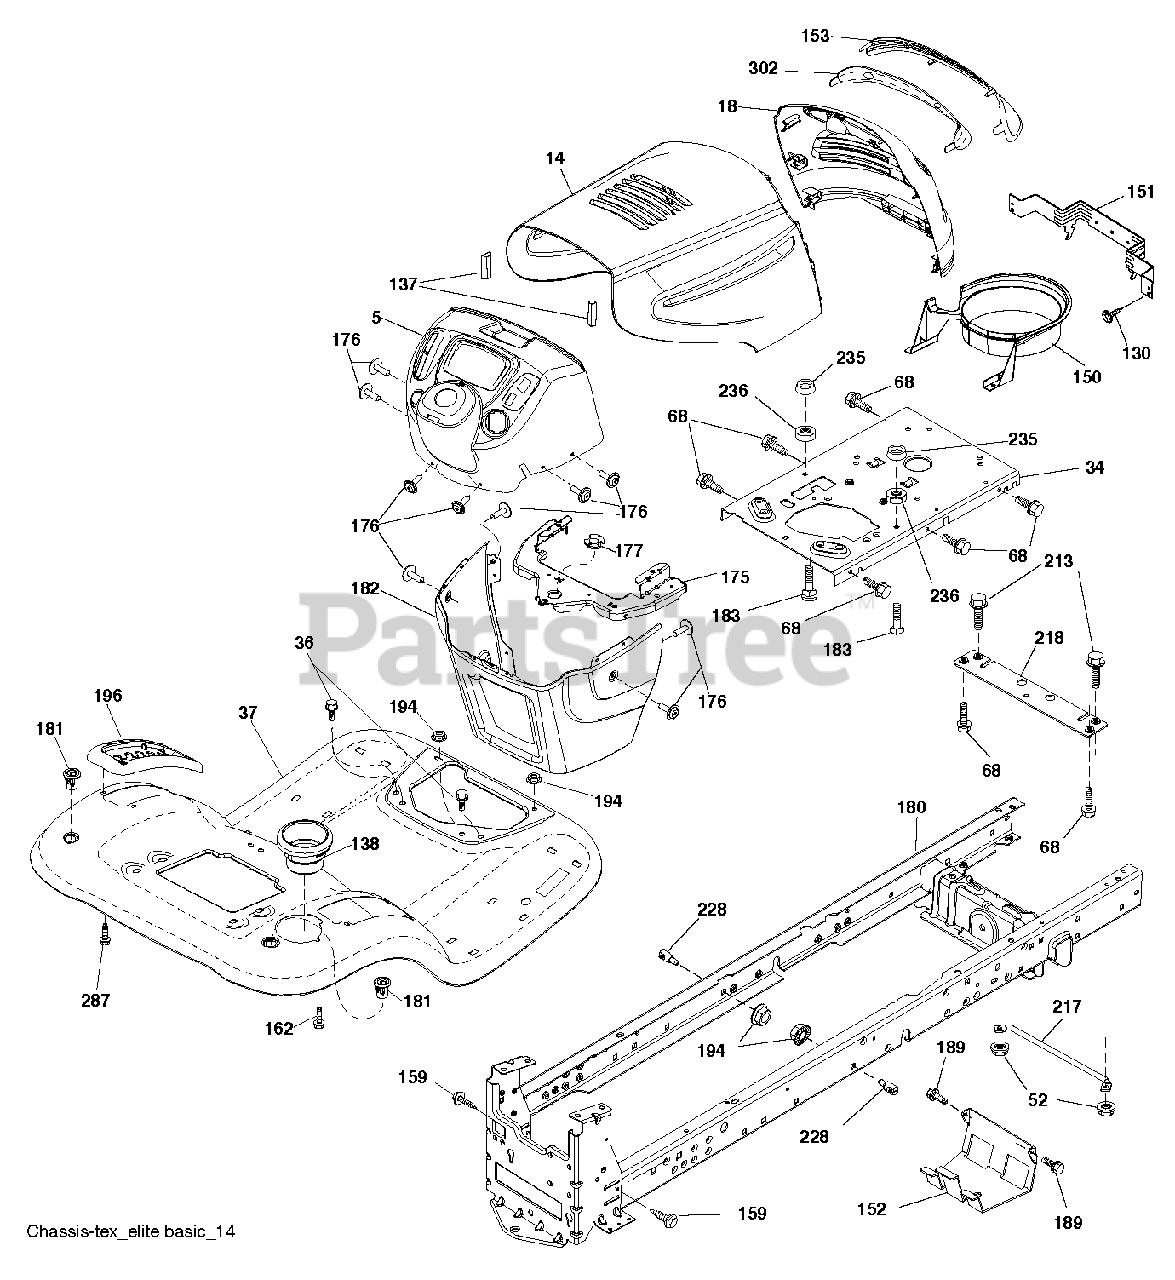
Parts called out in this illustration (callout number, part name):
5	DASH.P/L.TEX.CBL.CL.N/CHK.BLAC
14	HOOD.PNT.STL.ELITE.TOPLVRS.667
18	GRILLE.ELITE.BASIC.LT.BLACK
34	PLATE.ENGINE.WELDED.CHASSIS
36	SCREW 5/16"
37	FENDER.TLT.FS.W/CUPHLD.667
52	LOCKNUT
68	SCREW LT
130	SCREW.#10 X 0.750.BOS (2 2)
137	BUMPER.HOOD.LARGE.1.75"
138	CUPHOLDER.TL.TEX.BLACK
150	DUCT.INTAKE.AIR.KAW
151	BRACKET PIVOT
152	SHIELD.BROWNING.W/TEX
153	LENS.GRILLE.BASIC.BAR.LT.CLR
159	SCREW, 3/8-16X3/4
162	SCREW.HI-LO.CONSOLE
175	CROSSMEMBER.LT
176	SCREW.#10-24X5/8.RN.QU
177	BUSHING STEERING
180	CHASSIS
181	FEND/FTRST.PCH.CPH.NFW
182	DASH.LOWER.LT.CCS
183	BOLT.5/16-18X1-1/4 FULL.THREAD
189	SCREW
194	NUT LOCK HEX FLANGE 5/16-18
196	CONSOLE.ASM.DECKLFT.BL/RBT.TLT
213	BOLT
217	ROD.PIVOT.HOOD
218	X-PIECE.HOOD.STOP.NON/
228	STUD.FASTNER.W/ANTI-ROTATE
235	SPACER FENDER
236	NUT.CENTERLOCK.5/16-
287	SCREW 1/4X20
302	INSERT.LENS.REFLECTIVE.LEFT
